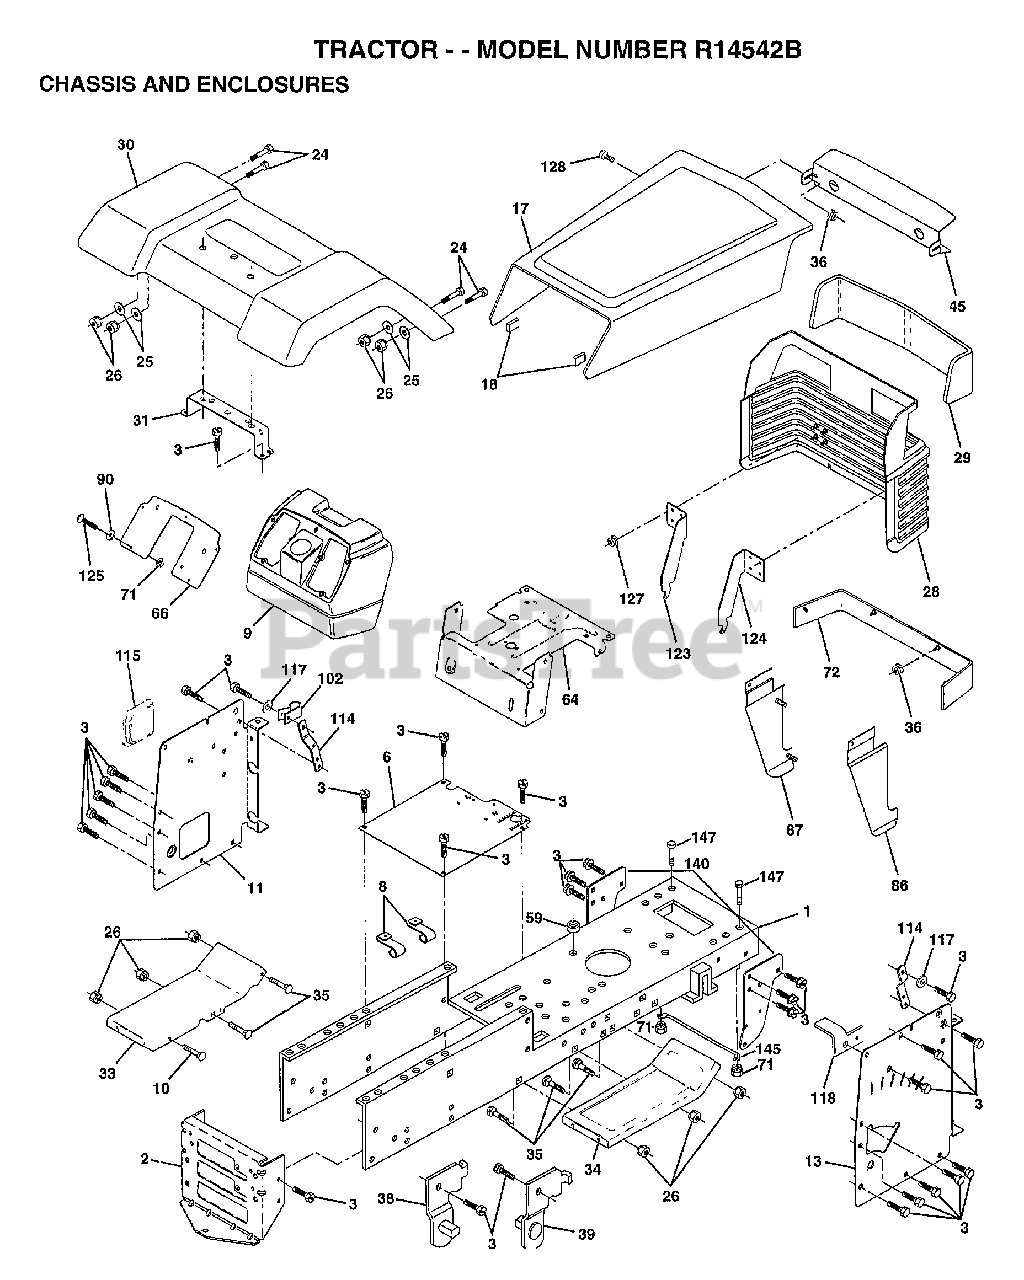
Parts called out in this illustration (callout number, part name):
1	CHASSIS ASM
3	SCREW
6	SADDLE
8	"CLIP,INSULATOR"
9	DASH.PLASTIC.BLK
11	PANEL.DASH.LH.
13	PANEL.DASH.RH.NOT
17	HOOD.ASM.YTGT.PNT
24	BOLT
25	WASHER
26	NUT
28	GRILLE ASM WELD
30	FENDER
31	BRKT FENDER
33	FOOTREST LH
34	FOOTREST RH
35	BOLT
36	PAL NUT LT
38	BRACKET ASM LH
39	BRACKET ASM RH
64	DASH.LOWER.LT
66	PLATE SLKSCR.OM
71	NUT HXKEP 1/4X20
72	STRAP GRILLE 505
86	PANEL.SIDE.RH.ASM
87	PANEL.SIDE.LH.ASN
90	WASHER PM
102	CLIP T
114	BRACKET.SUPT.DASH
115	COVER ACCESS
117	WASHER.SERRATED.
118	BRACKET.CLUTCH.MC
123	BRACKET.PICK.LH.
124	BRACKET.PICK.RH.
125	SCREW
127	PAL NUT
128	SCREW SPECIAL
140	BRKT SUSPENSION
145	"ROD POVOT,CHASSIS"
147	BOLT LT
